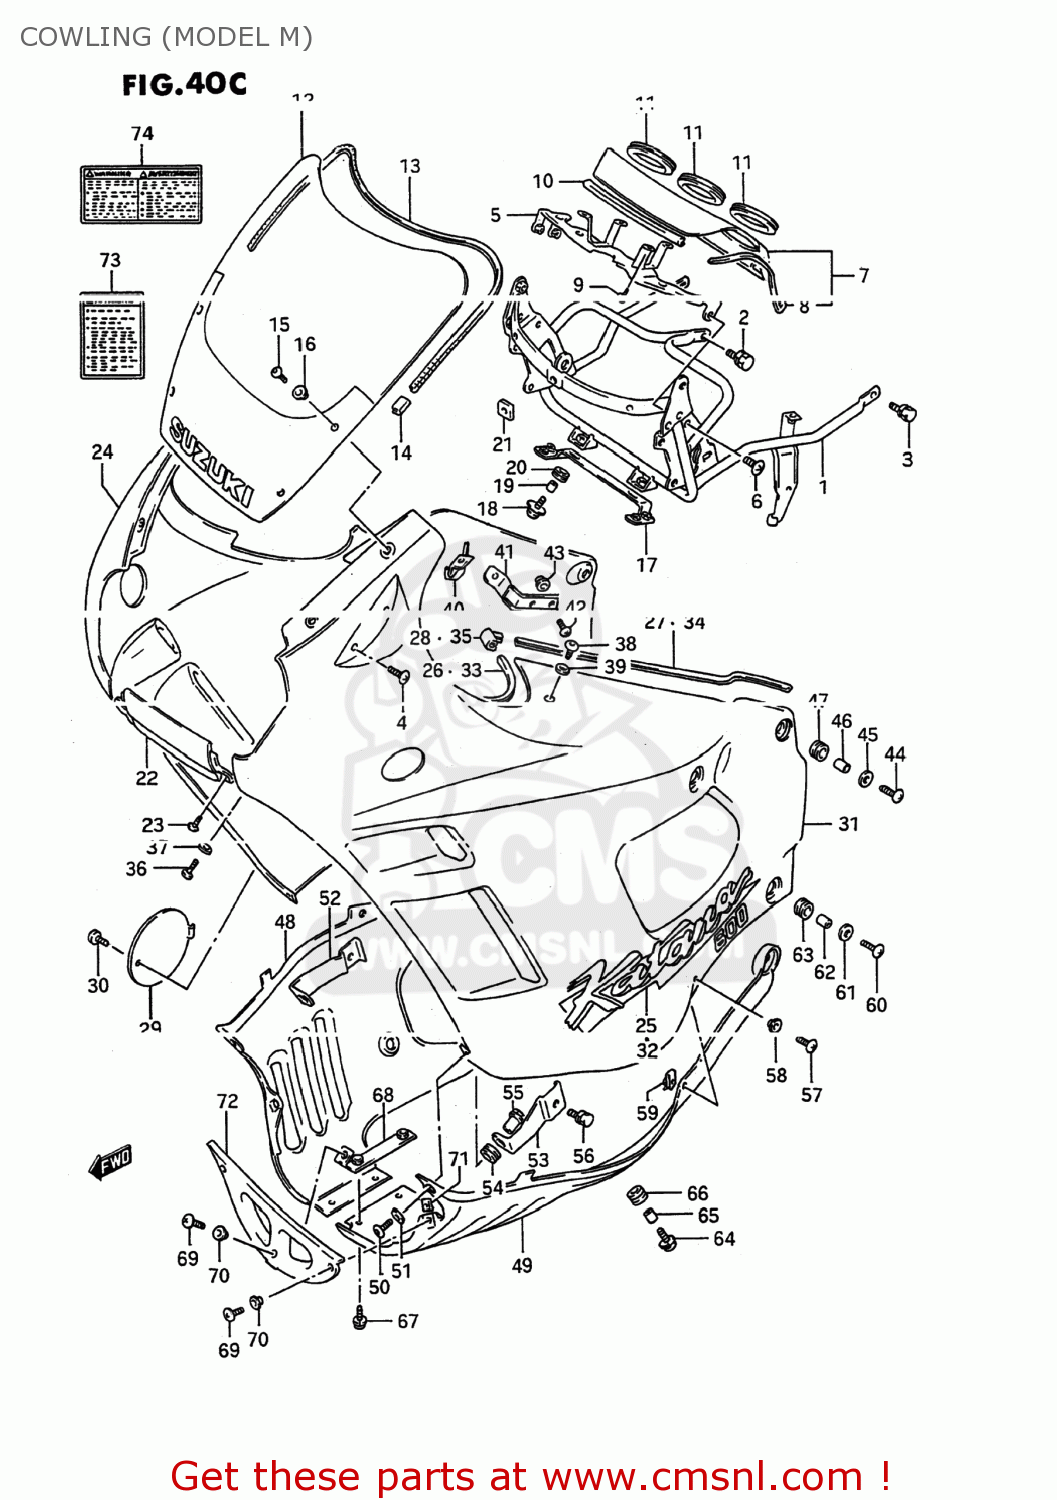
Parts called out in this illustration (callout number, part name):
1	BRACE,COWLING
2	BOLT
3	BOLT 6X12
4	SCREW 6X12
5	PLATE,METER FITING
6	SCREW 6X12
7	COVER,METER
8	MOLDING
9	SCREW 5X8
10	MOLDING,METER COVER
11	CUSHION,METER COVER
12	WINDOW,COWLING
13	MOLDING
14	CAP,MOLDING END
15	SCREW
16	WASHER(5.2X11X1)
17	PLATE,COWL CTR PANEL
18	SCREW(6X20)
19	SPACER (6,8X10X9.4)
20	CUSHION
21	CUSHION,SCREEN
22	PANEL,COWLING CTR
23	SCREW
24	COVER ASSEMBLY,COWLING,RIGHT
25	EMBLEM,COWLING SIDE,KATANA
26	MOLDING
27	MOLDING
28	JOINT,MOLDING END
29	LID,OIL
30	SCREW(6X16)
31	COVER ASSEMBLY,COWLING,LEFT
32	EMBLEM,COWLING SIDE,KATANA
33	MOLDING
34	MOLDING
35	JOINT,MOLDING END
36	SCREW(6X25)
37	WASHER(6.5X18X1.5)
38	SCREW(6X16)
39	WASHER(6.3X16X1.5)
40	BRACKET,COWLING UPR,R
41	BRACKET,COWLING UPR,L
42	SCREW(6X25)
43	NUT,COWLING SIDE BRKT
44	SCREW(6X25)
45	WASHER(6.5X18X1.5)
46	SPACER (6.1X9X9)
47	CUSHION
48	COVER,COWLING,UNDER,RIGHT
49	COVER,COWLING,UNDER,LEFT
50	SCREW(6X30)
51	WASHER(6.5X18X1.5)
52	BRACKET,COWLING LWR,R
53	BRACKET,COWLING LWR,L
54	CUSHION
55	NUT,COWLING,FR
56	BOLT
57	SCREW(5X14)
58	WASHER(5.2X14X1.5)
59	NUT,HEADLAMP HOUSING,UPPER
60	SCREW(6X25)
61	WASHER(6.5X18X1.5)
62	SPACER(6.1X9X12.3)
63	CUSHION
64	SCREW(6X20)
65	SPACER (6.1X9X9)
66	CUSHION
67	SCREW, LOWER
68	BRACKET,FR UNDER COWL
69	SCREW
70	WASHER(5.2X14X1.5)
71	NUT,HEADLAMP HOUSING,UPPER
72	COVER,COWLING UNDER FR
73	LABEL (WARNING SCREEN)
74	LABEL,GENERAL WARNING
75	LABEL (TIRE INFORMATION)
